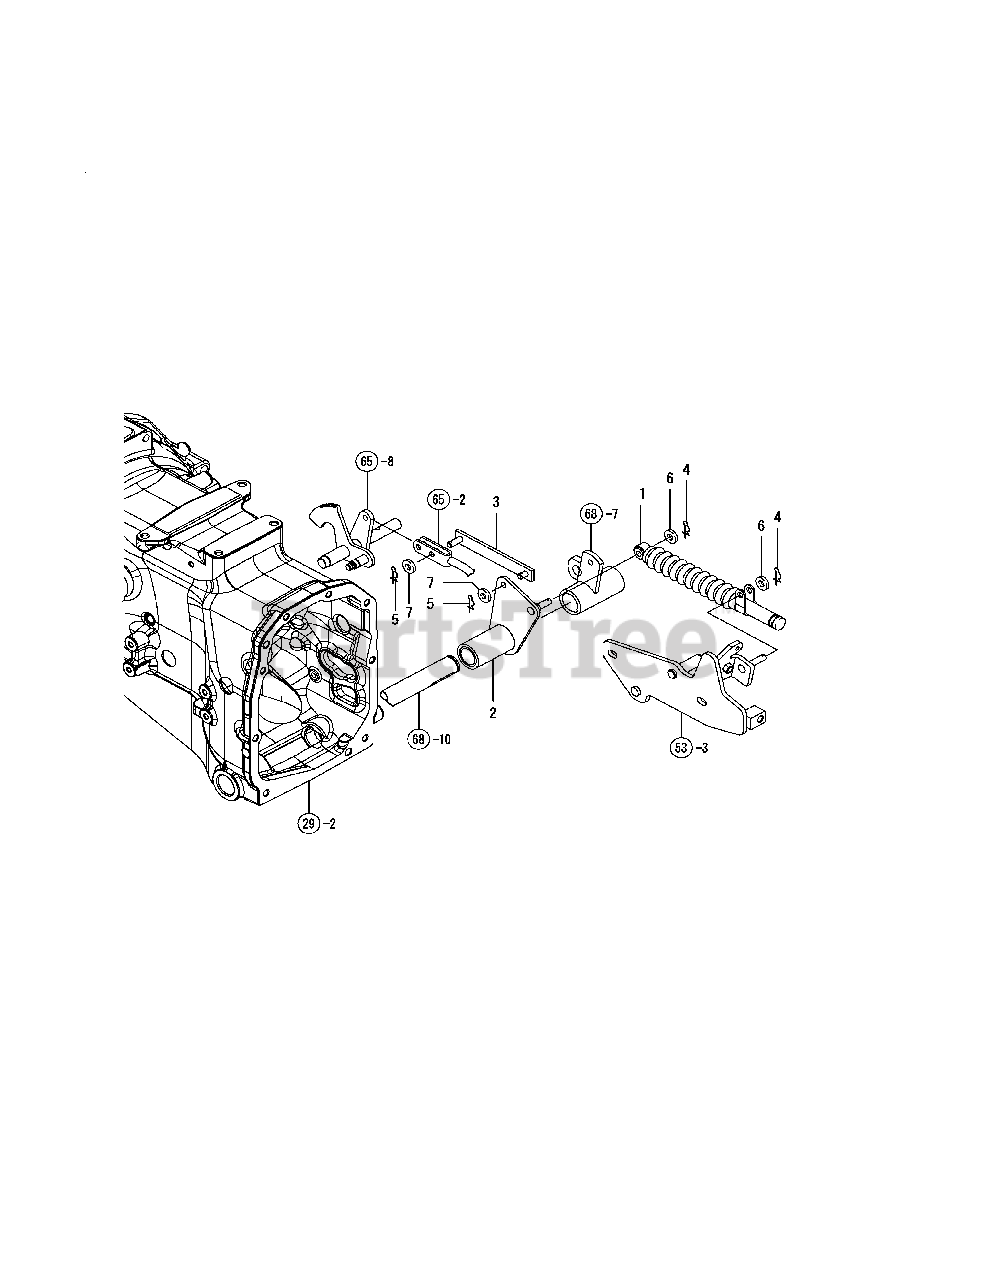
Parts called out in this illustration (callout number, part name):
1	SHOCK ABSORBER
2	CRANK, DAMPER CMP
6	WASHER 8, POLISHED
7	WASHER 8, POLISHED
